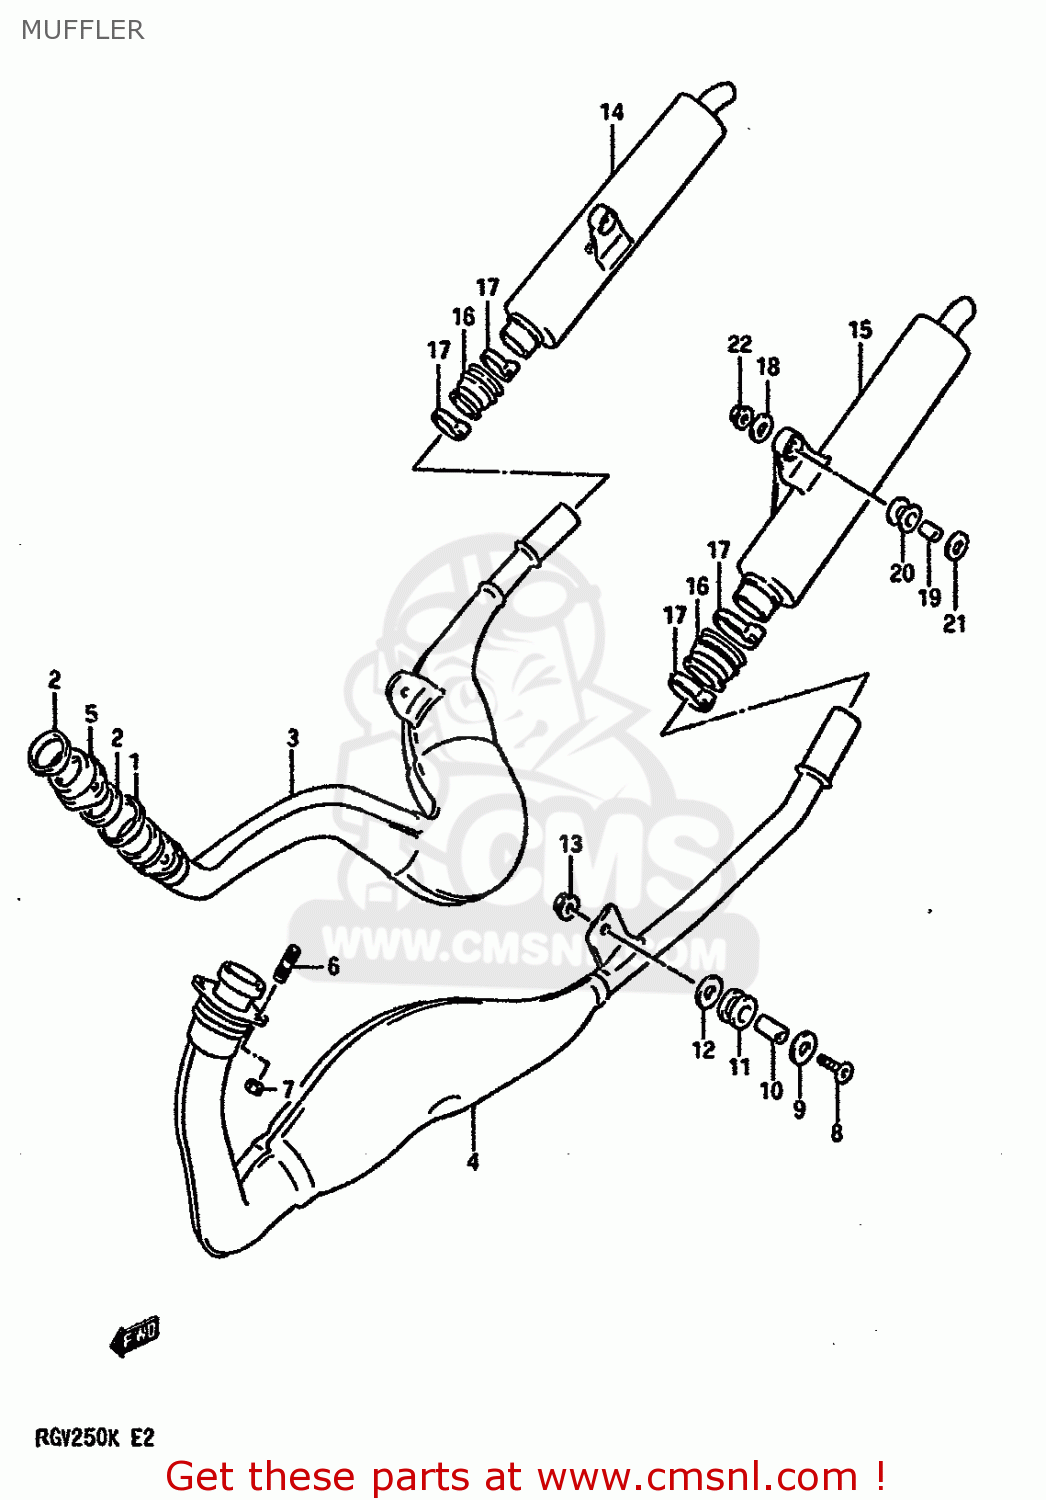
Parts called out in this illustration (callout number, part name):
1	GASKET,EXHAUST PIPE (MCA)
2	GASKET,EXHAUST PIPE (NAS)
3	BODY,MUFFLER 1ST RH
4	BODY,MUFFLER 1ST LH
5	FLANGE,EXHAUST FITTING
6	STUD BOLT
7	NUT
8	BOLT(8X28)
9	WASHER (8.2X24X1.6)
10	SPACER (8.8X12X13.5)
11	CUSHION
12	WASHER
13	NUT M8
14	BODY,MUFFLER 2ND RH
15	BODY,MUFFLER 2ND LH
16	CONNECTOR,MUFFLER
17	CLAMP
18	WASHER
19	SPACER (8.6X12X17.5)
20	CUSHION
21	WASHER
22	NUT M8
